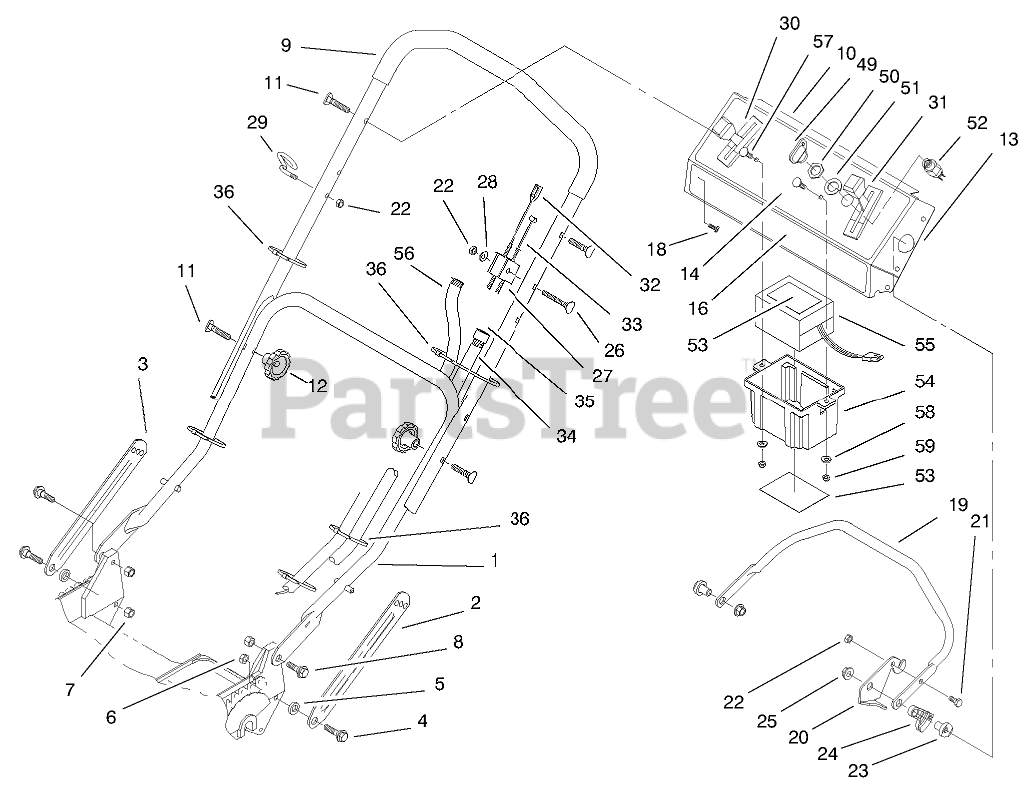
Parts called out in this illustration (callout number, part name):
1	ASM-Handle
2	Latch-Handle
3	Latch-Handle
4	SCREW-SHOULDER
5	SPACER
6	NUT-LOCK, NI
7	NUT-LOCK, NI
8	SCREW-SHOULDER
9	HANDLE - DIPPED
10	DECAL-PANEL, REAR
11	SCREW-HANDLE
13	Panel-Control (Incl. Ref. #10,14, & 16)
14	DECAL - INSTRUCTION
16	DECAL - PANEL
18	SCREW-TAP
19	BAR-CONTROL
20	Lever-Control
21	SCREW-HH
22	NUT-LOCK, NI
23	SPACER-SUPPORT
24	LEVER-TRACTION
25	NUT-LOCK NI
26	SCREW-HANDLE
27	SUPPORT-CABLE
28	WASHER-FLAT
29	GUIDE-ROPE
30	CONTROL-SPEED, GROUND
31	THROTTLE CONTROL
32	BRAKE CONTROL
33	CABLE-TRACTION
34	CONTROL CABLE COVER
35	FITTING-RING
36	TIE-CABLE
49	KEY-IGNITION
50	NUT-HH
51	WASHER-TOOTH, INTERNAL
52	Switch-Starter (Incl. Ref. #50,51)
53	DECAL-BATTERY
54	COVER - BATTERY
55	BATTERY ASSEMBLY
56	WIRE HARNESS
57	SCREW-CARR
58	WASHER-FLAT
59	NUT-LOCK, NI
